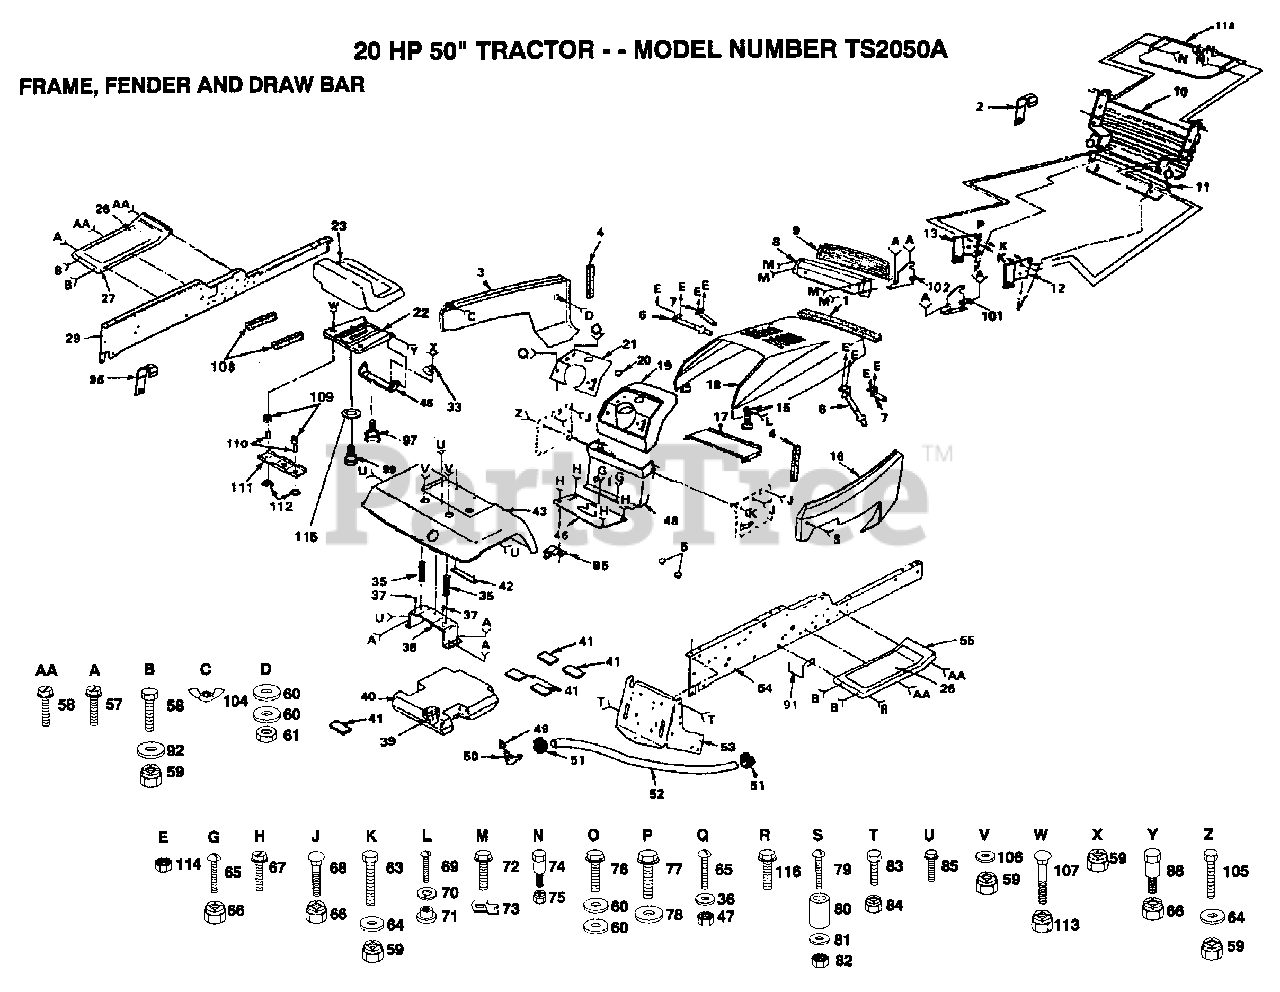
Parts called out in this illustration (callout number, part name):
1	FOAM STRIP T
4	FOAM STRIP T
5	CAP SPRING
9	LENS LT
12	SUPPORT RH YTH
13	SUPPORT LH YTH
15	HOOD LATCH T
16	"PANEL,SIDE RH "
20	PLUG-DASH T
26	FOOTREST PAD
33	CLIP T
35	SPRING COMPRESSIO
36	WASHER
37	NUT-PUSH YT
41	PAD-SPACER LT
43	FENDER
46	COVER GATE SHIFT
48	DASH ASSEMBLY
49	BUSHING OUTLET T
50	FUEL TANK STEM GT
51	HOSE CLAMP
57	SCREW
60	WASHER PM
63	BOLT
64	WASHER
65	SCREW
67	SCREW
68	BOLT
69	SCREW
70	LOCKWASHER
71	WELDNUT
73	"""J"" FASTENER LT"
76	SCREW
77	SCREW
78	WASHER
79	SCREW
80	SPACER LT
81	WASHER
83	BOLT
84	NUT GTV
85	SCREW LT
91	BELT RETAINER GT
92	WASHER
97	"KNOB 1/2"" YT"
99	"BOLT,SHOULDER"
101	SUPPORT RH YTH
102	SUPPORT LH YTH
106	WASHER
108	STRIP FORM
109	SPRING COMPRESSED
110	SPACER SPLIT
111	BRKT SWITCH
112	BUSHING
114	NUT
115	WASHER
116	SCREW GTV
118	"SHIELD,HEAT"
